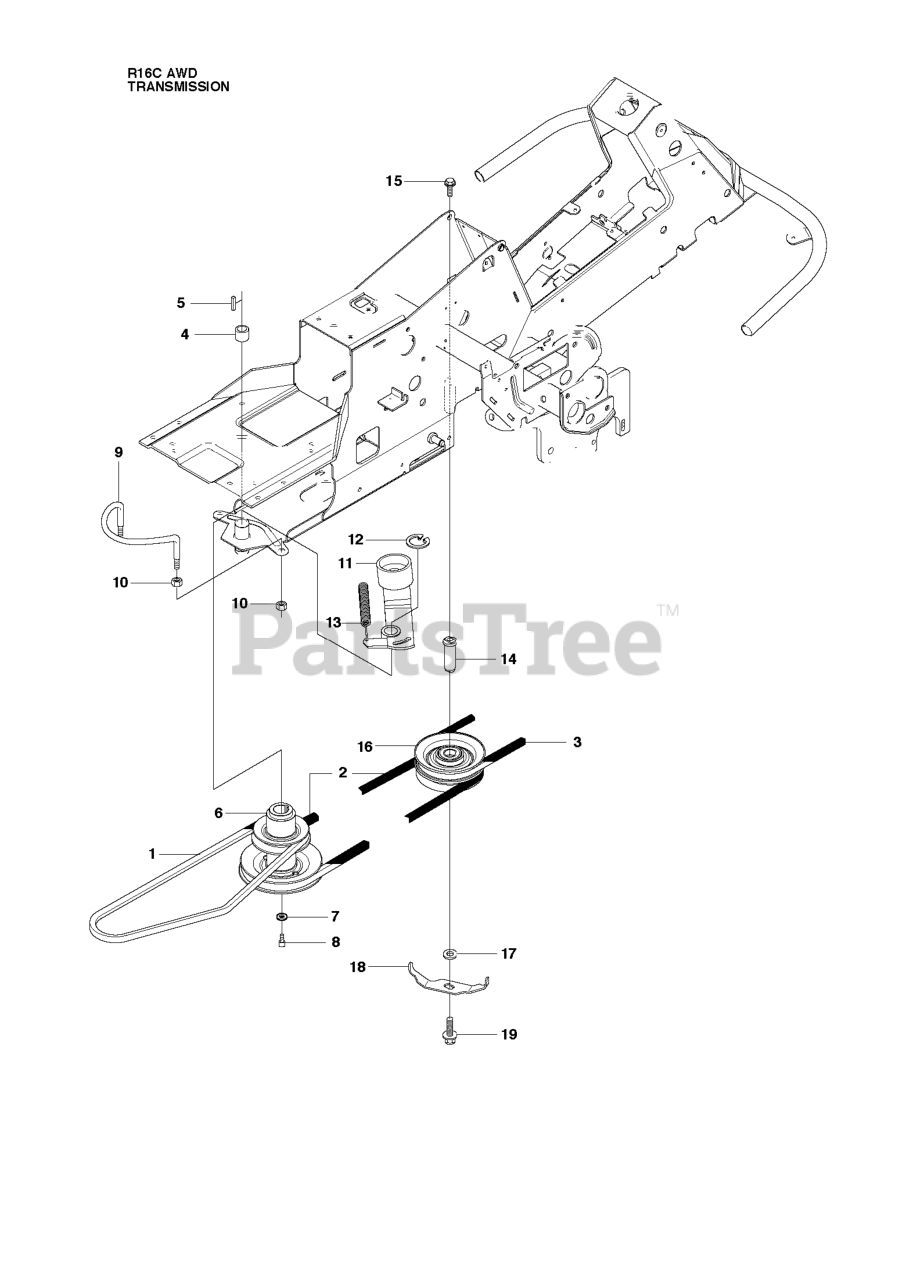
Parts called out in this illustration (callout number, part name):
9	BELT GUIDE
10	NUT
12	RETAINING RING SGA 25
14	SHAFT
18	BELT GUIDE
19	BOLT
